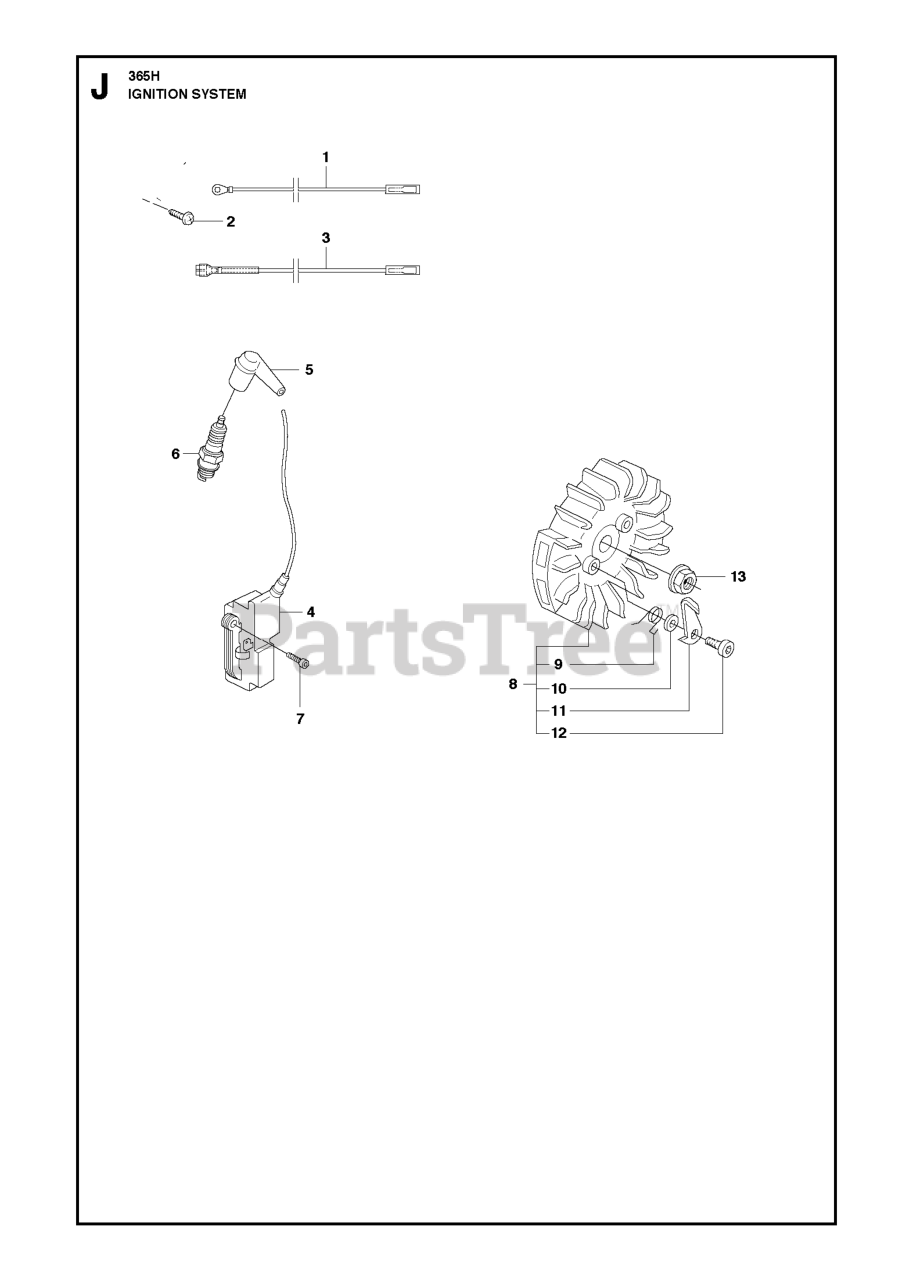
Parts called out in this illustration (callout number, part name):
4	IGNITION MODULE
5	SPARK PLUG CONN. KIT
6	SPARK PLUG RCJ7Y
6	SPARK PLUG M14X1.25 NGK BPMR7A
12	SCREW M5X14
13	NUT W/ WASHER
